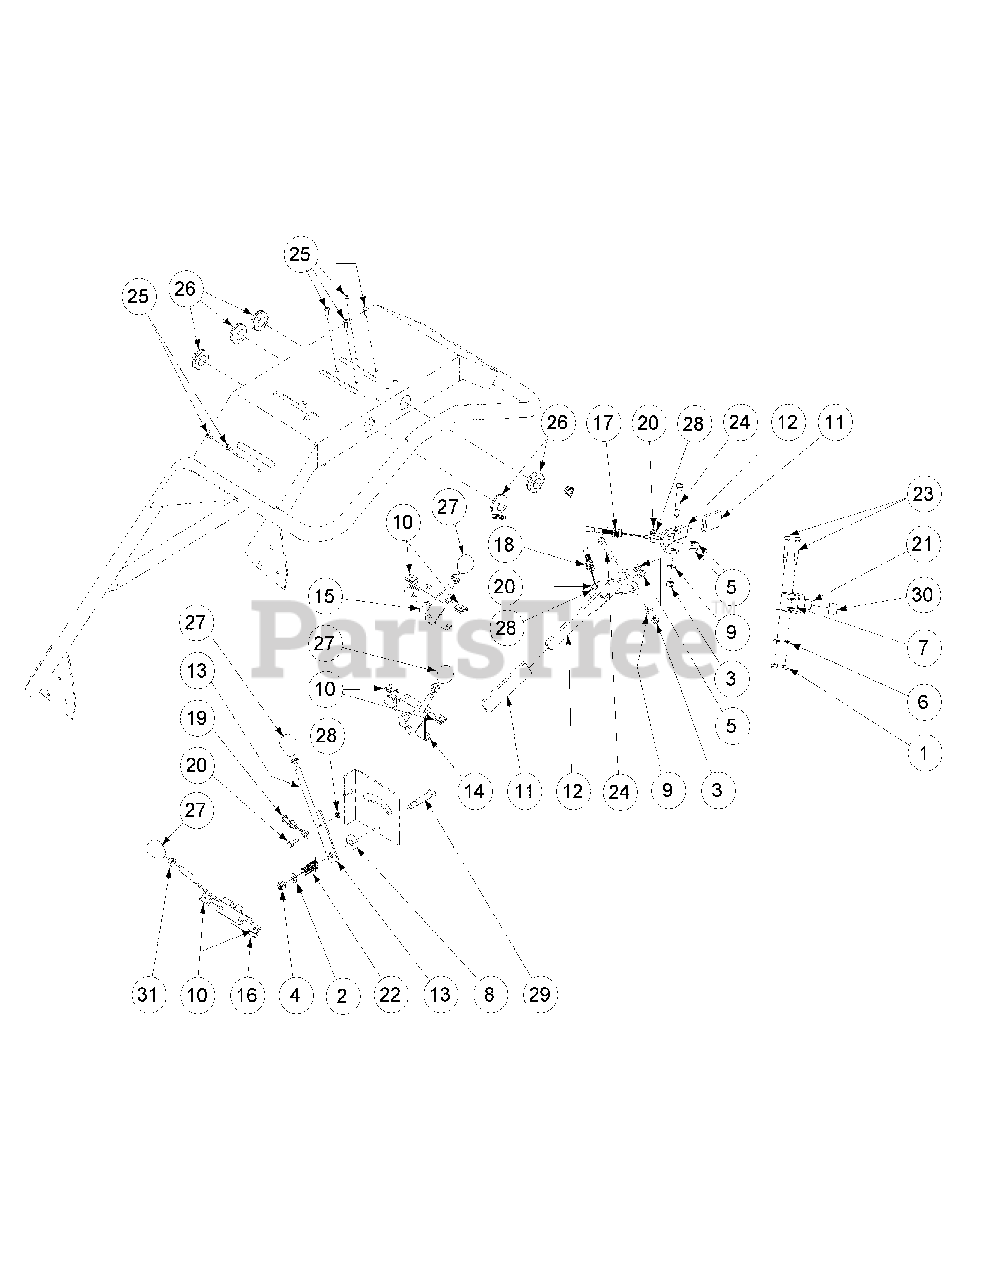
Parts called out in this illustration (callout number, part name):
1	Nut, #10-24
2	Washer, 5/16
3	Nut, 1/4-20
4	Nut, 5/16-18
5	Washer, 5/16
6	Washer, 3/16
7	Washer, 1/4, SS
8	Idler Washer
9	Washer, 1/4 x .630 x .0515
10	U-Nut, #10-16
12	Control Lever Weldment
13	On/Off Lever Weldment
14	3rd Hole Control
15	Remote Deflector Cable
16	Throttle Control
17	Forward Cable 74.25" LG
18	Reverse Cable 94.25" LG
19	On/Off Cable
20	Shoulder Bolt, 1/4 x 1/4
21	Speed Control Lever
22	Compression Spring
23	Shoulder Bolt, 1/4 x 1.25
24	Shoulder Bolt, 5/16 x 1.50
25	Hex Cap Screw, 10-24 x .50
26	Rubber Grommet
27	On/Off Lever Knob
28	Nut, 10-24, w/Star Washer
29	Shoulder Bolt 3/8 x 1.50
30	Speed Control Grip
31	Jam Nut, 3/8-16
